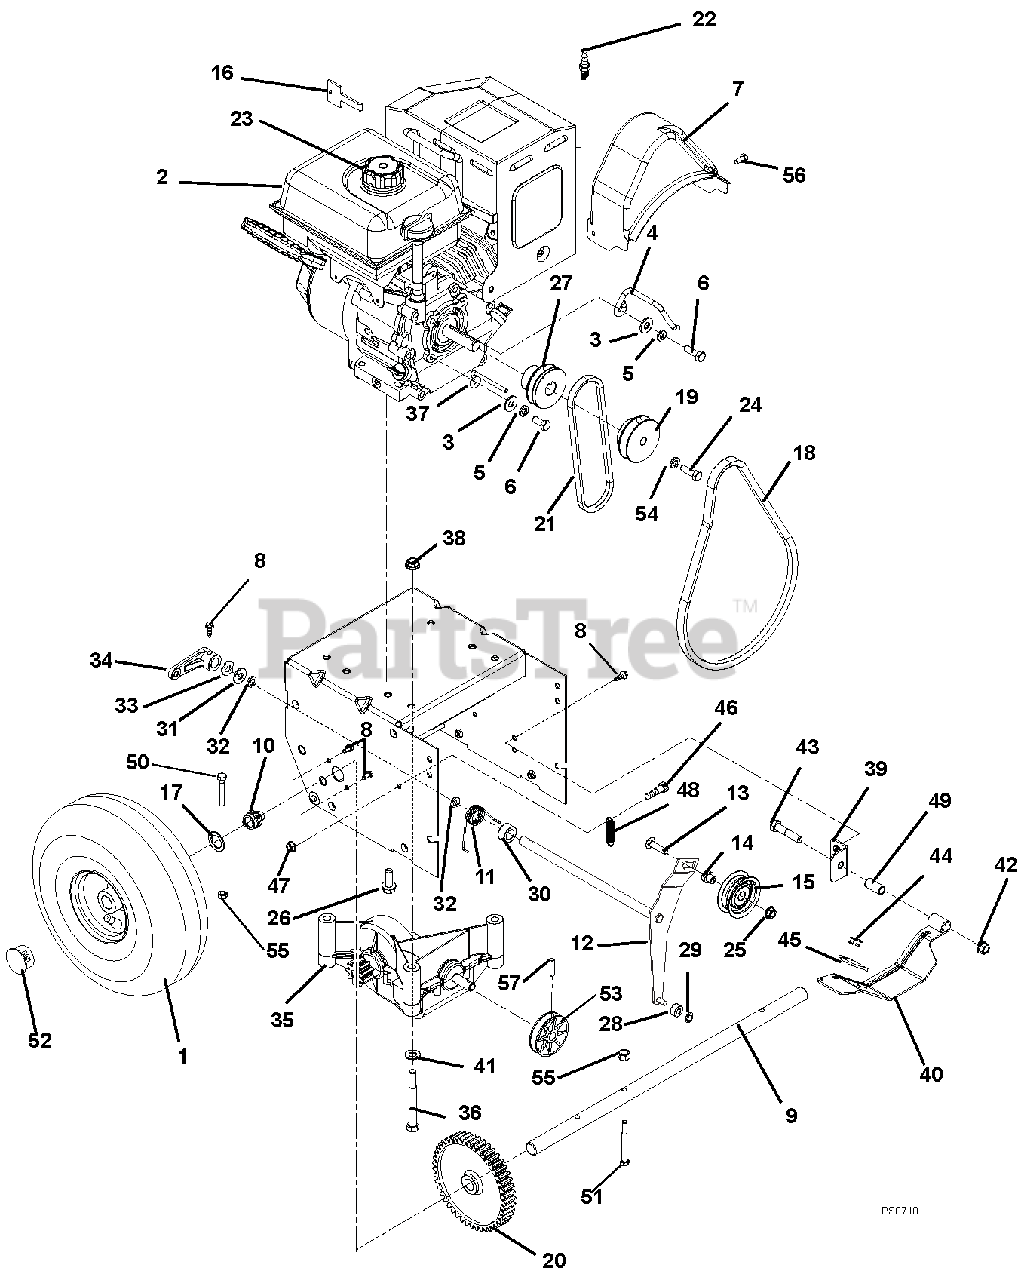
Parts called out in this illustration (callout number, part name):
1	TIRE/WHEEL, 4.10-4
2	ENGINE,LCT STORMFORCE 208 RECL
3	@WSHR-FL-STL.38X.875X.083 YWZC
4	FINGER, BELT
5	WSHR-LK .312X.097 HVY YWZC
6	BLT-HEX .31-24X.75 YWZC GR5
7	COVER, BELT
8	SCR-TAP .25-20X.50 HWH TR YWZ
9	SHAFT, AXLE - SINGLE SPEED
10	BSHG .75X1.125X.65
11	SG-TORS .067X.88
12	WELDMENT, ATTACHMENT IDLER ARM
13	@BLT-RHDSHSQNK.31-18X1.25 G5YZ
14	SPCR, BRG .315X.50X.688X.281
15	IDLER
16	KEY, PUSH/PULL LCT (2/PACKAGE)
17	WSHR-FL-STL.754X1.125X.062YWZC
18	V-BELT, 4L-RAW EDGE
19	SHEAVE, ENGINE
20	GEAR, AXLE 45T POLYMER
21	V-BELT, 3L-STRETCH FIT
22	PLUG, SPARK
23	CAP, FUEL TANK BLACK
24	BLT-HEX .38-24X1.0 YWZC GR5
25	@NUT-LK-TOP-FLG .31-18 YWZC
26	SCR-TAP .38-16X1.0 HWH YZ W/VT
27	SHEAVE, DRIVE
28	BSHG,SLV .270 X .750 X .250
29	RG-RTNG-EXT .250X.010
30	BSHG-SLV .510X.751X.475
31	WSHR-FL-STL .52X.827X.062 YWZC
32	BUSHING, POLYLINER-.50 SNAPIN
33	WSHR-WAVE .50X.75X.015 .13FRHT
34	ARM, CLUTCH - ATTACHMENT
35	TRANSMISSION, GT H0 W/O PULLEY
36	@BLT-HEX .38-16X3.50 GR5 YWZC
37	BELT FINGER
38	NUT-LK-CTR-FLG .38-16 YWZC
39	BRACKET, MOUNT - BRAKE
40	ARM, BRAKE
41	@WSHR-FL-STL.406X.812X.065 YWZ
42	@NUT-LK-TOP-FLG .38-16 YWZC
43	@BLT-HEX .38-16X1.75 GR5 YWZC
44	RVT-POP .187 YZ
45	PAD, BRAKE
46	BLT-SHLDR .31X.50 .25-20X.438
47	@NUT-SPNLK-FLG .25-20 YWZC
48	SG-TENS .06X.46X2.00
49	BSHG-SLV .385X.500X1.045
50	BLT-HEX .25-20X1.75 GR8 YWZC
51	@BLT-HEX .25-20X2.5 GR8 YWZC
52	PLUG, HOLE - 0.75"
53	PULLEY, COMPOSITE 3L (2.308)
54	@WSHR-LK .38X.094 REG YWZC
55	@NUT-LK-CTR .25-20 YWZC
56	SCR-TAP .25-20X.50 LGHWH TR YZ
57	PIN-ROLL, 5MMX26MM
